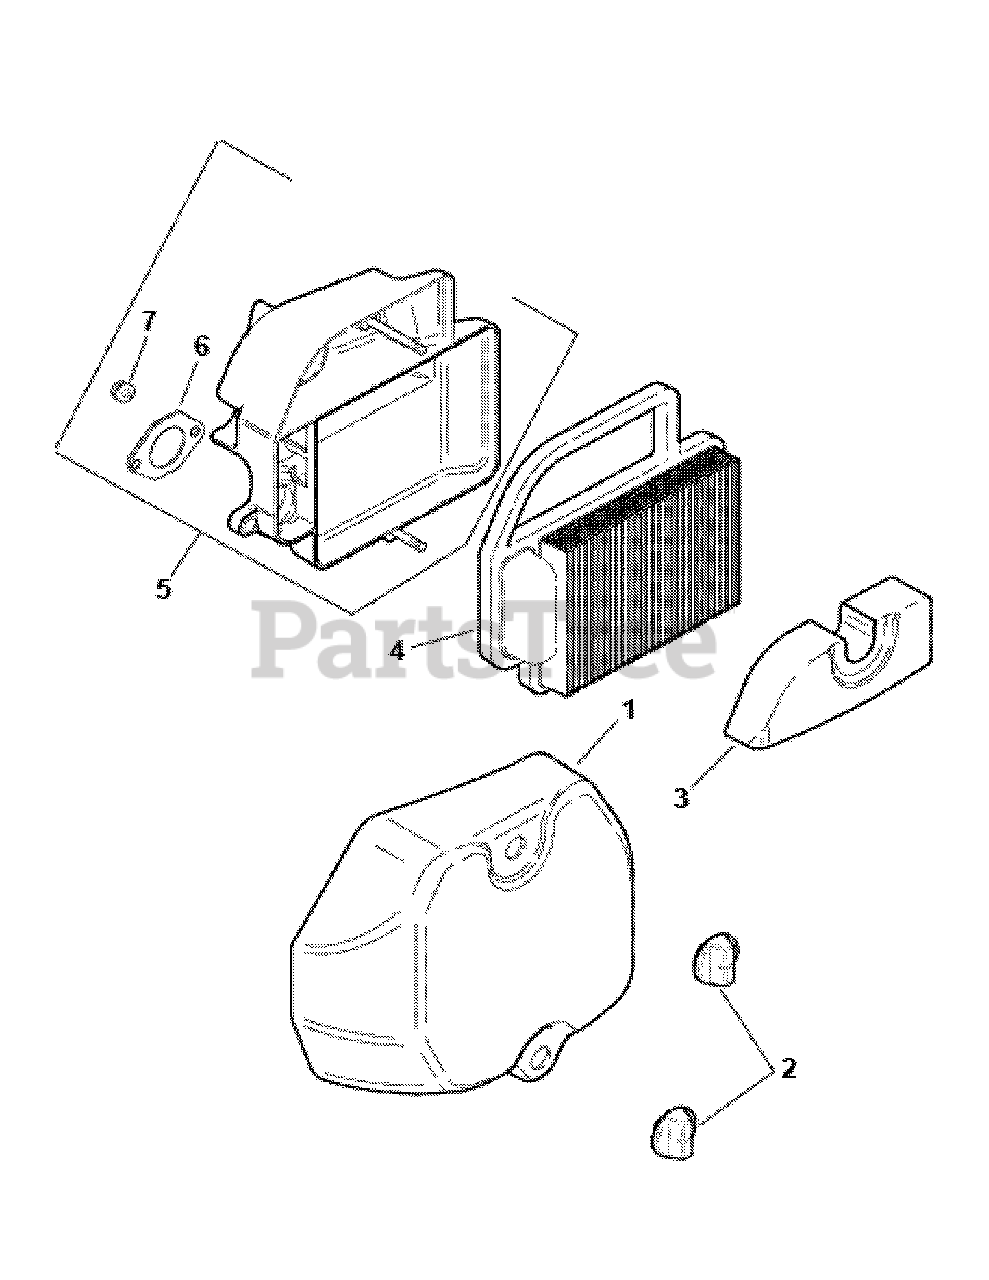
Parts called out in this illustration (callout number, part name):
1	Air Cleaner Cover
3	Precleaner Element
4	Air Cleaner Element
5	Air Cleaner Base Kit
6	Air Cleaner Base Gasket
